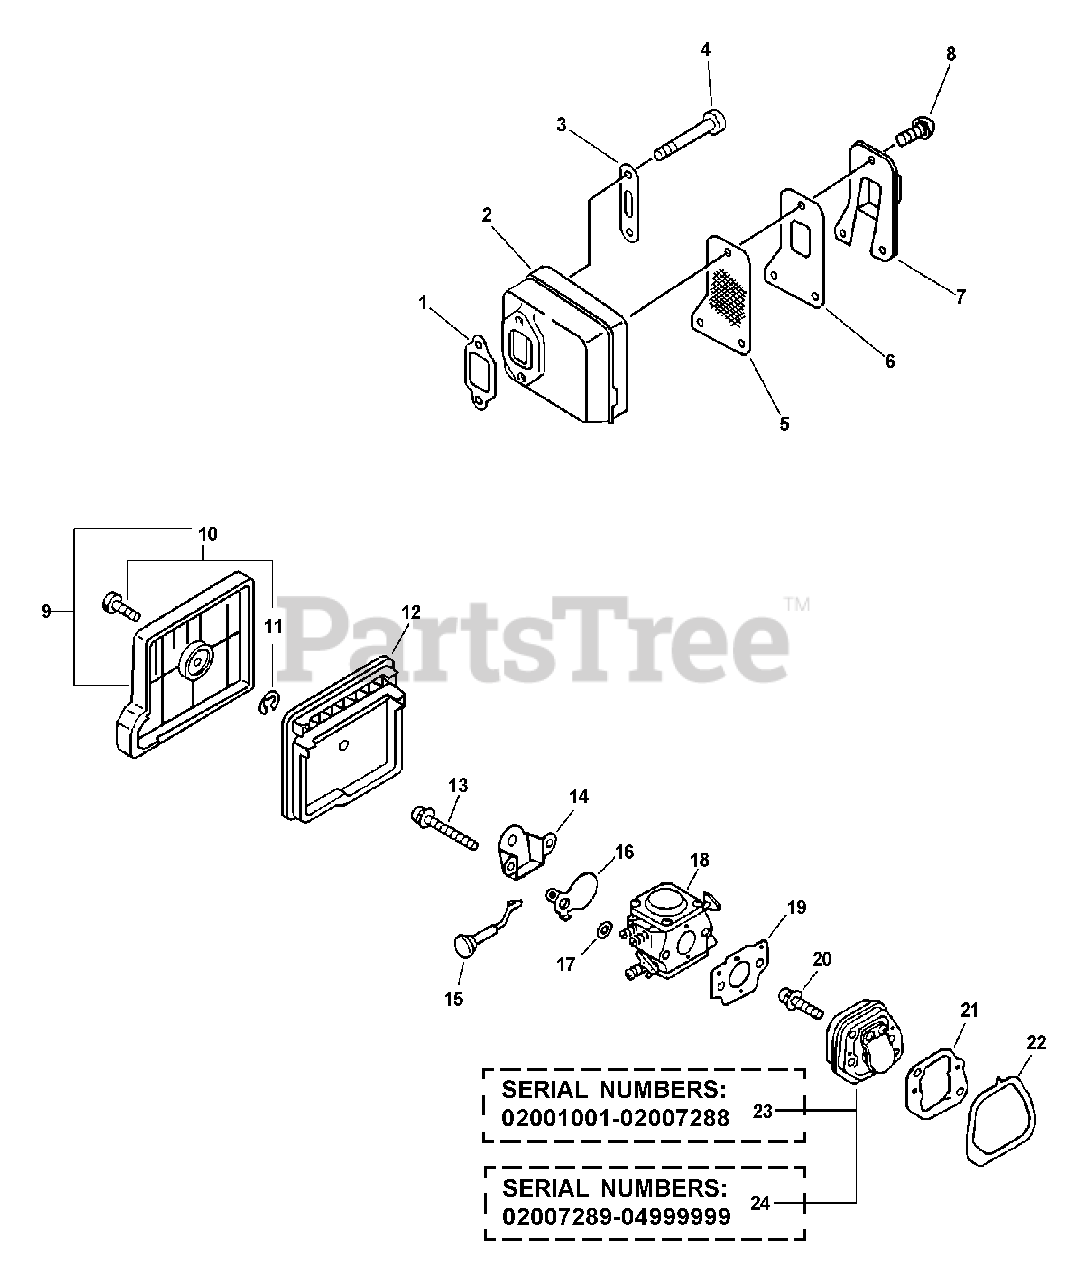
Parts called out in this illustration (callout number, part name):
1	GASKET, MUFFLER
2	MUFFLER
3	PLATE, EYE
4	BOLT, FLANGE HSH 5×45
5	SCREEN, SPARK ARRESTER
6	GASKET, EXHAUST
7	COVER, MUFFLER
8	SCREW 4×12
9	COVER ASSY, AIR FILTER
10	THUMBSCREW
11	E-RING 4
12	FILTER, AIR
13	SCREW 5×45
14	PLATE, PREVENT
15	ROD, CHOKE
16	SHUTTER, CHOKE
17	WASHER 5.5×8×0.8
18	CARBURETOR - WT-589
19	GASKET, INTAKE
20	SCREW 5×18
21	GASKET, INTAKE
22	SEAL, INTAKE
23	INSULATOR KIT
24	INSULATOR KIT
